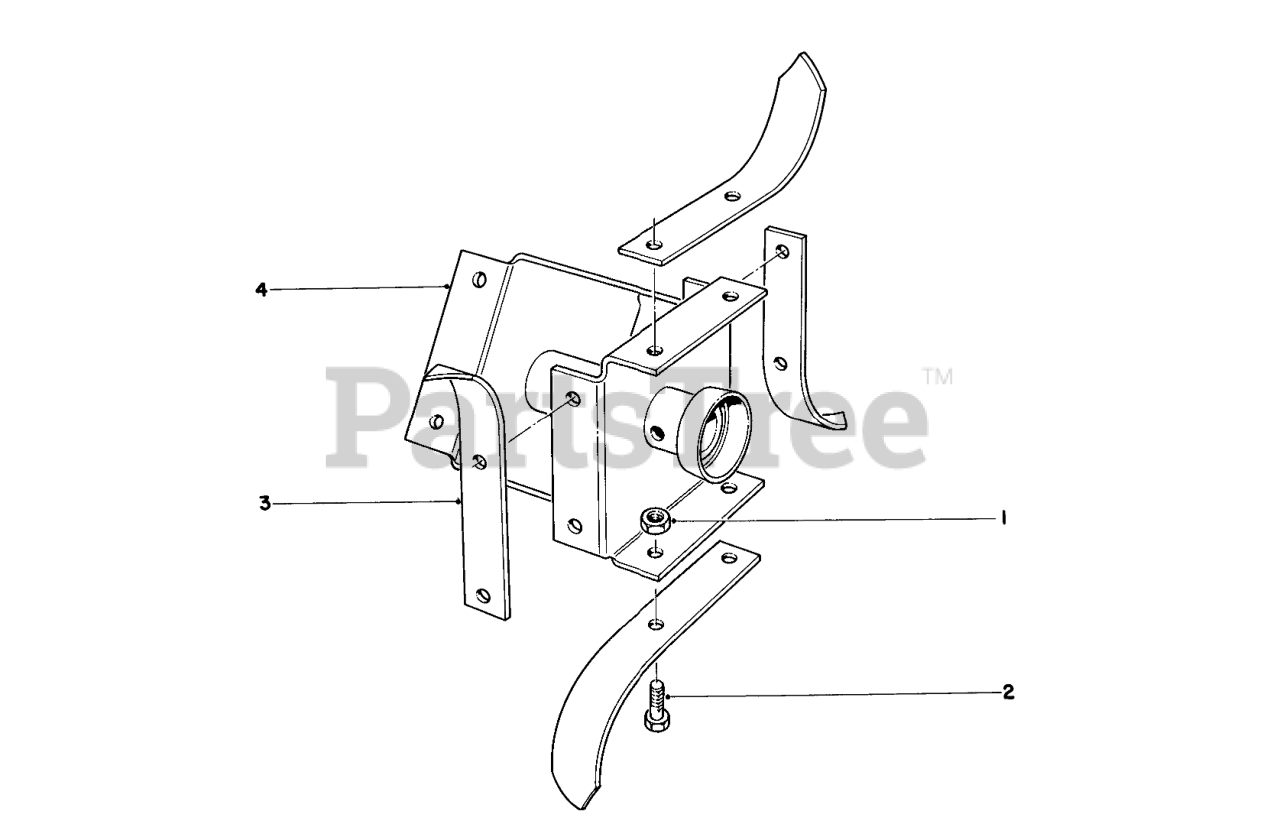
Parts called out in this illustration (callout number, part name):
1	NUT-LOCK, CONE
2	Capscrew
3	Pick Tine
4	Axle Welded R.H.
